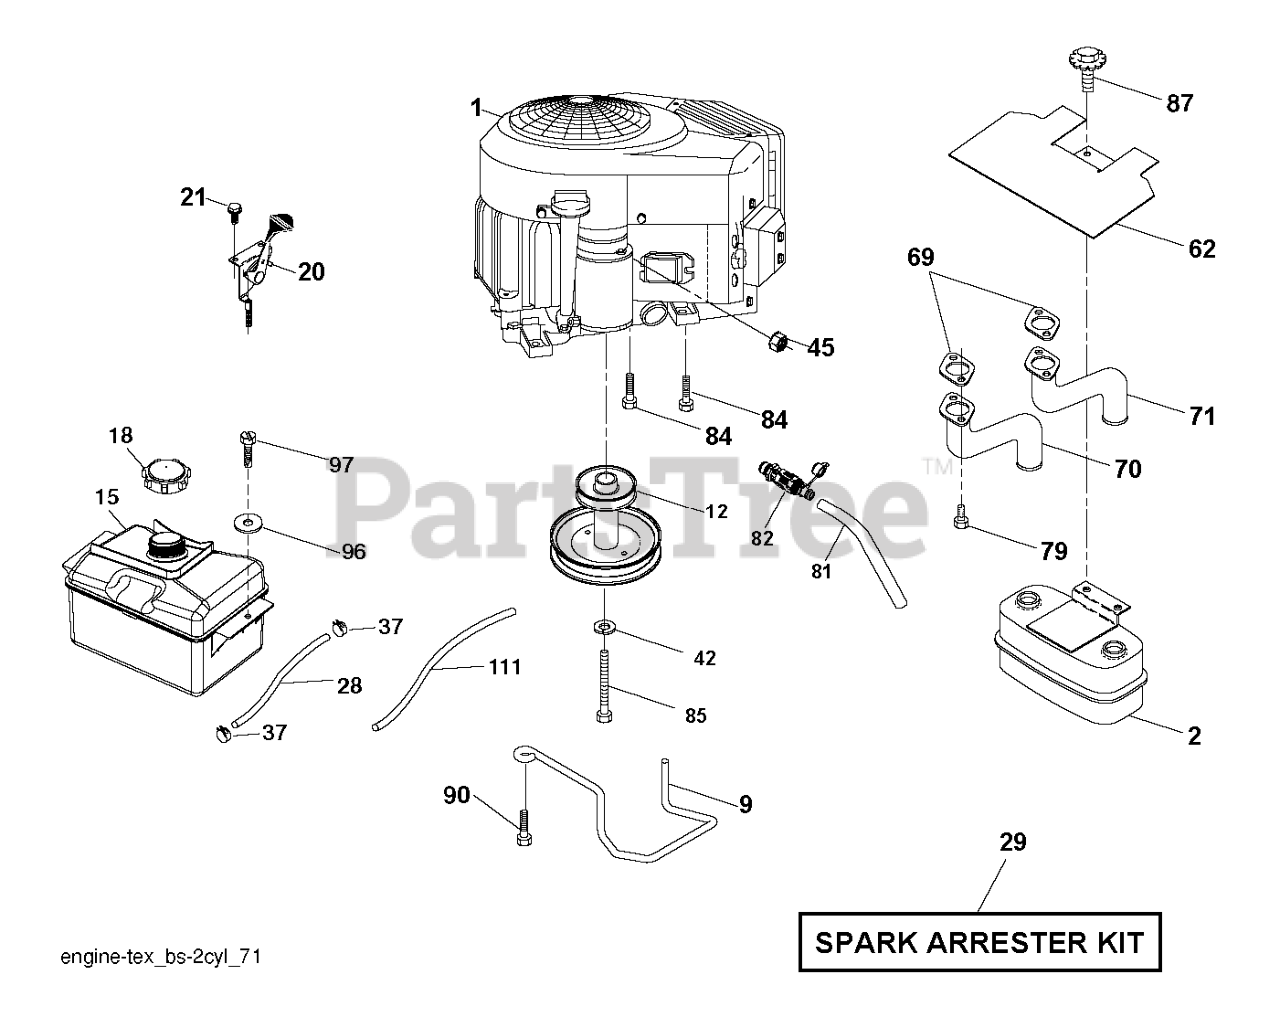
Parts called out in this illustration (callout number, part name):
2	MUFFLER.TWIN.CYL.LOW.TONE
9	KEEPER.BELT.ENGINE.4.2
12	PULLY ENGINE
15	TANK.ASM.FRT.2.5 GAL.W/CAP.EPA
18	CAP.2.25'.VENTED.TETHER .EPA
20	CONTROL.TH/CK.COBRA.B&S.TWN.BK
21	SCREW.#10 X 0.750.BOS
28	LINE.FUEL.20"FRONT.EMI
29	KIT.SPARK ARRESTOR 794945 B&S
37	HOSE CLAMP
42	LOCKWASHER
45	NUT
62	SHIELD.HEAT.MUFFLER
69	GASKET.MUFFLER
70	EXHAUST.TUBE.LH.BS/TWIN
71	EXHAUST.TUBE.RH.B&S.TWIN.INTEK
79	SCREW.SOCKET.HEAD.5/16-18
81	TUBE, DRAIN OIL ASM.
82	VALUE.OIL.DRAIN
84	SCREW.3/8-16
85	BOLT HEX 7/16-20X4-1/4"
87	BOLT.5/16-18UNCX3/4 W/SEMS.BLK
90	SCREW 3/8-16X1
97	SCREW HEXWSHR 1/4-20X3/4
111	RP PURGE LINE
